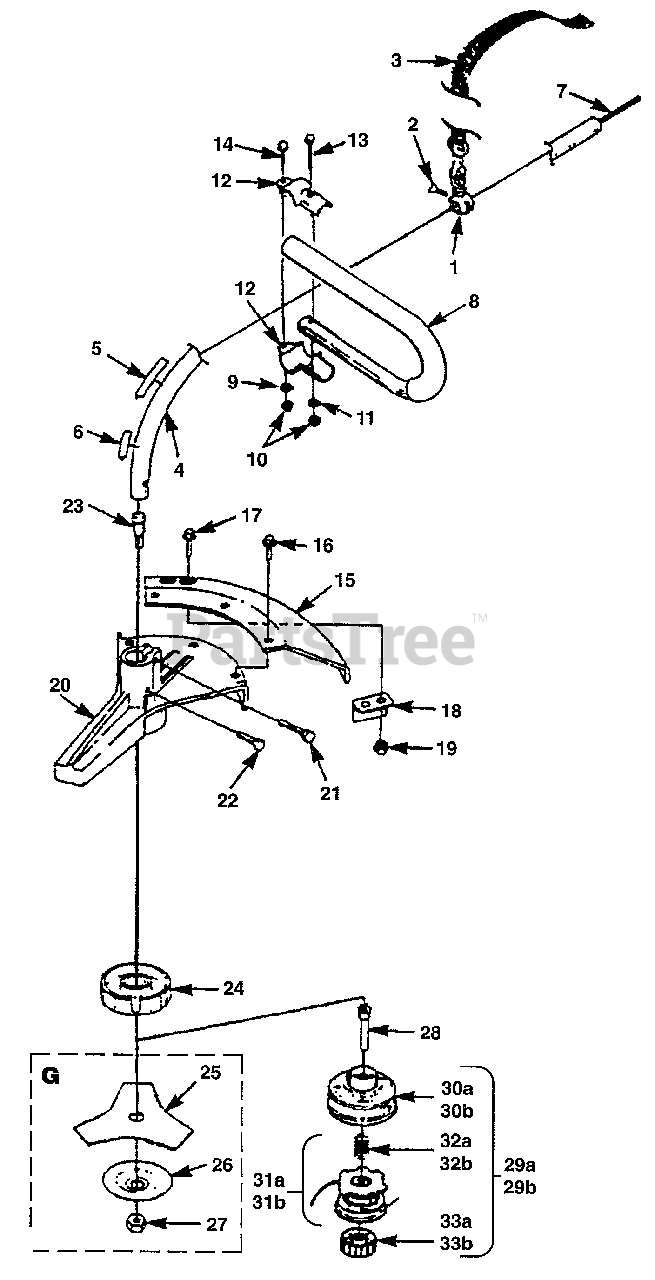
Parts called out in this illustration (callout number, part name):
1	BRACKET-Hanger
2	SCREW-Thumb (10-24 X 1/2")
3	HARNESS w/Connector
4	HOUSING-Drive Shaft (Black)
5	DECAL-Starting Instructions
6	DECAL-Warning
7	SHAFT-Flexible
8	HANDLE BAR ("J")
9	WASHER-Flat
10	NUT-Hex (1/4-20)
11	WASHER-Lock (1/4")
12	CLAMP-Handle Bar
13	SCREW-Sems Hex Hd. (1/4-20 X 1")
14	SCREW-Sems Hex Hd. (1/4-20 X 1/2")
15	DEFLECTOR-Grass
16	SCREW-Machine Hex Hd. (1/4-20 X 1/2")
17	SCREW-Machine Hex Hd. (10-24 X 3/8")
18	BLADE-Cut-Off
19	NUT-Hex (10-24)
20	HOUSING-Lower Bearing
21	SCREW-Sems Hex Hd. (1/4-20 X 1")
22	SCREW-Machine Hex Hd. (10-24 X 3/8")
23	SHAFT-Spindle
24	WASHER-Flanged
25	BLADE-Tri-Arc (8")
26	WASHER-Cupped
27	NUT-Hex Locking (R.H.)
28	CONNECTOR-Drive
29A	STRINGHEAD-Complete (.080" Line)
29B	STRINGHEAD COMPLETE (.095" Line)
30A	HOUSING & EYELET (Dual Line)
30B	HOUSING & EYELET (Dual Line)
31A	SPOOL & STRING & SPRING (.080" Line)
31B	SPOOL & STRING & SPRING (.095" Line)
32A	SPRING-Compression
32B	SPRING-Compression
33A	RETAINER-Spool (R.H. Thread, Black)
33B	RETAINER-Spool (R.H. Thread, Black)
G	BLADE KIT
